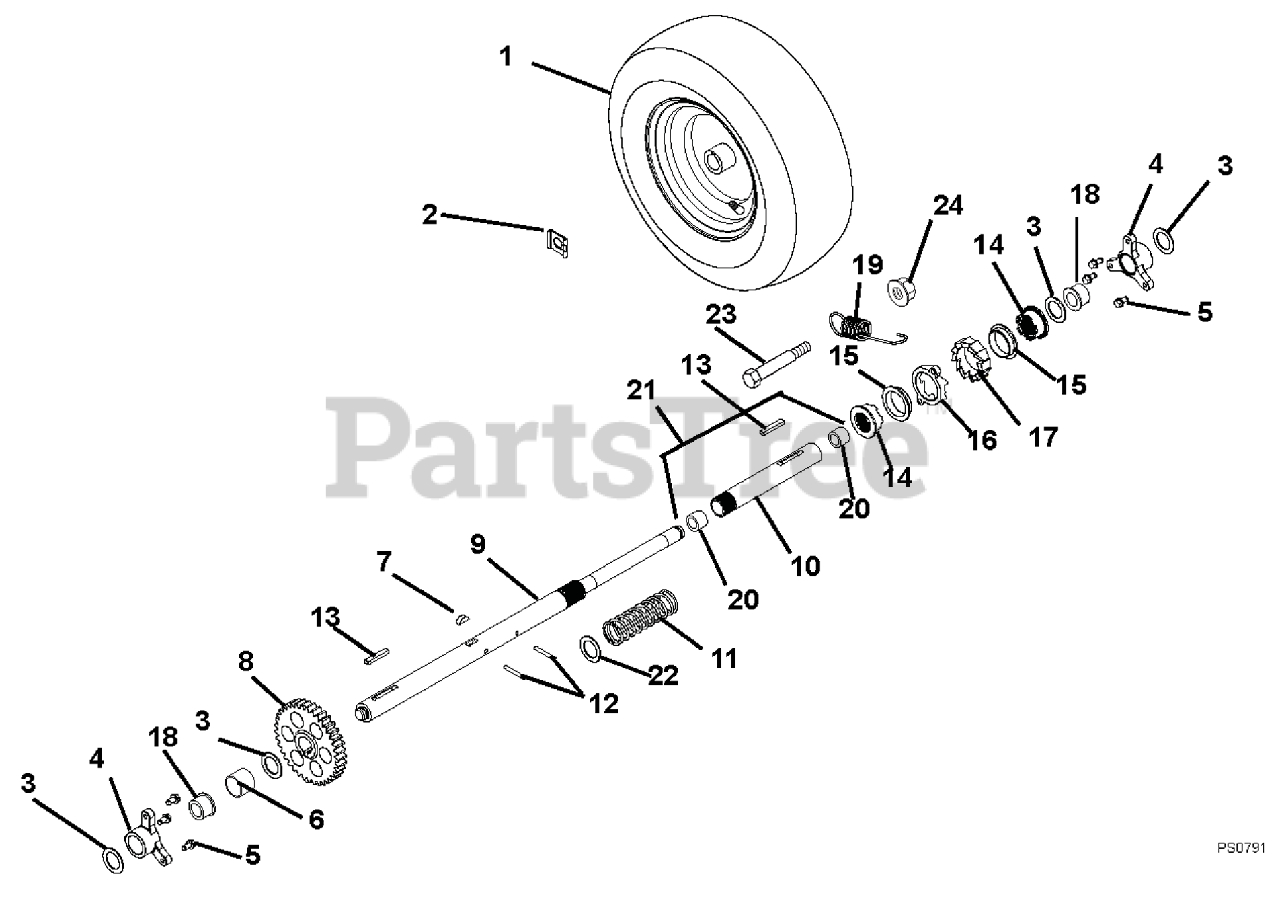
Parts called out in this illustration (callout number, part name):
1	TIRE/WHEEL,RH 15X5.00-6 REMOTE
2	CLIP, SNAP .625 DIA
3	WSHR-FL-STL 1.010X1.505X.062YZ
4	BUSHING, RAKE SHAFT 1"
5	SCR-TAP .25-20X.50 HWH TR YWZ
6	BSHG-SLV, 1.012X1.125X1.00
7	KEY-WDRF .25X.750X.313 SAE91
8	GEAR, SPUR
9	AXLE, LONG - CLICKER
10	AXLE, SHORT - CLICKER
11	SPRING, COMPRESSION
12	PIN-ROLL .188X1.25
13	KEY-RECT .25X.188X1.00
14	CLUTCH, DOG - SLIDING
15	BUSHING, FLANGE
16	GEAR, CLUTCH
17	GEAR, RATCHET
18	BSHG-FLG SPLIT NYLINER 1.0" HP
19	SG-TENS .06X.62X2.94
20	BSHG-SLV .706X.764X.75 BRZ
21	AXLE, CLICKER W/BUSHINGS
22	WSHR-FL-STL 1.010X1.250X.068YZ
23	BLT-SHLDR .50X1.50 .38-16X.625
24	@NUT-LK-TOP-FLG .38-16 YWZC
